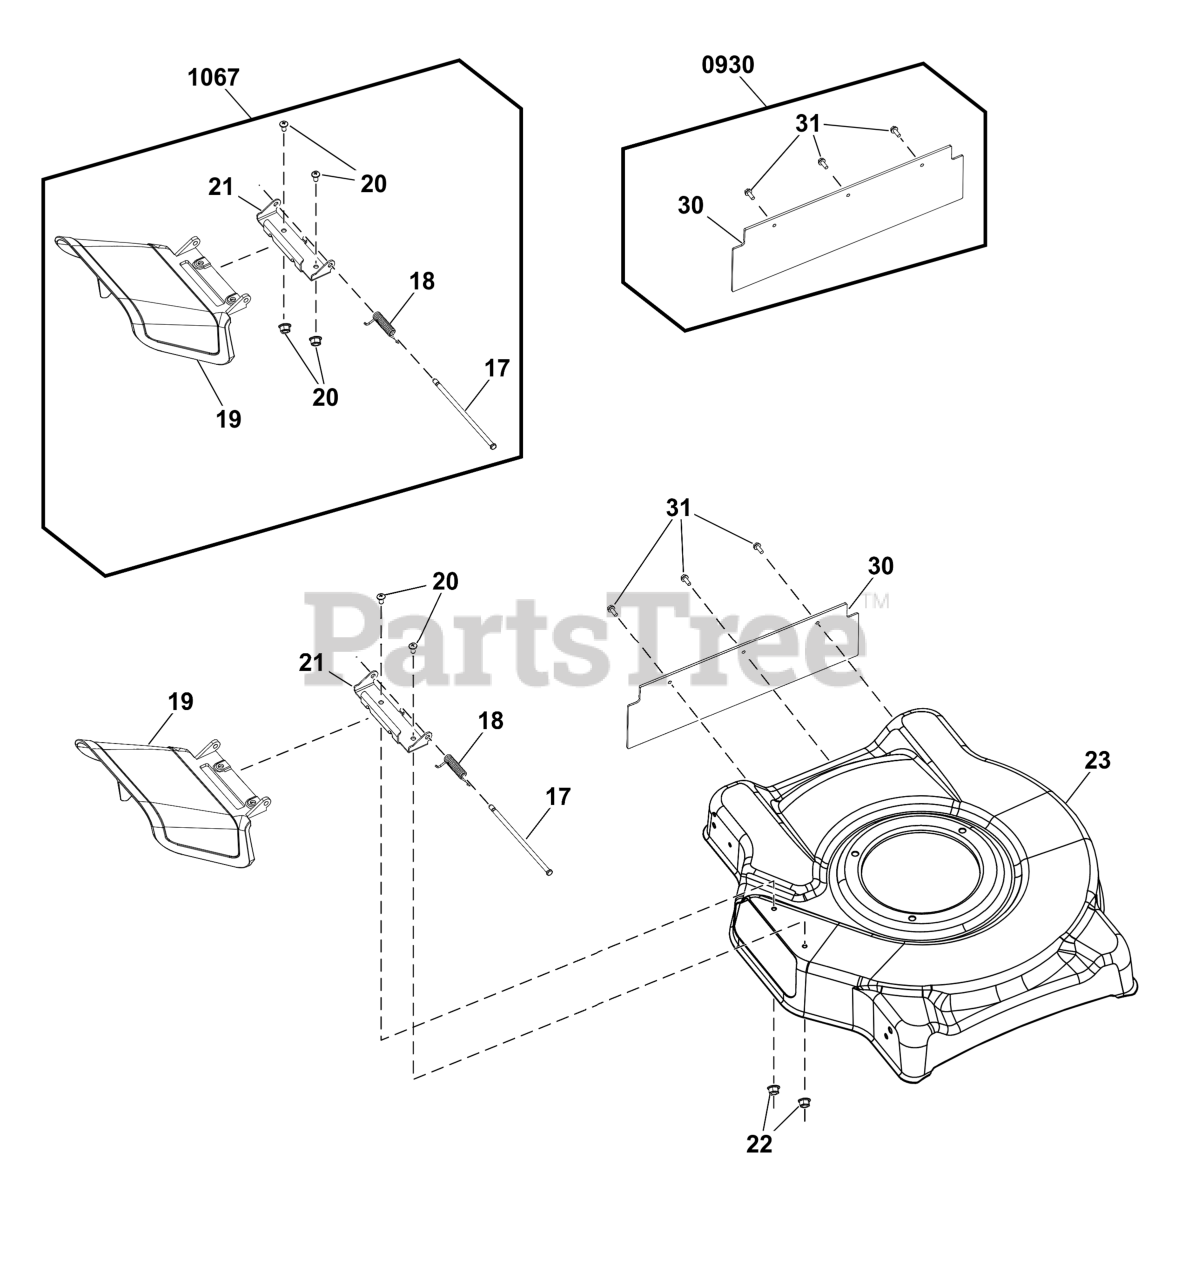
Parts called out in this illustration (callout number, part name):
17	SHAFT, Deflector
18	SPRING, Deflector
19	DEFLECTOR
20	SCREW
21	BRACKET, Deflector
22	NUT, Lock
23	DECK
30	COVER, Dust
31	SCREW
0930	KIT, Dust Cover
1067	KIT, Deflector
